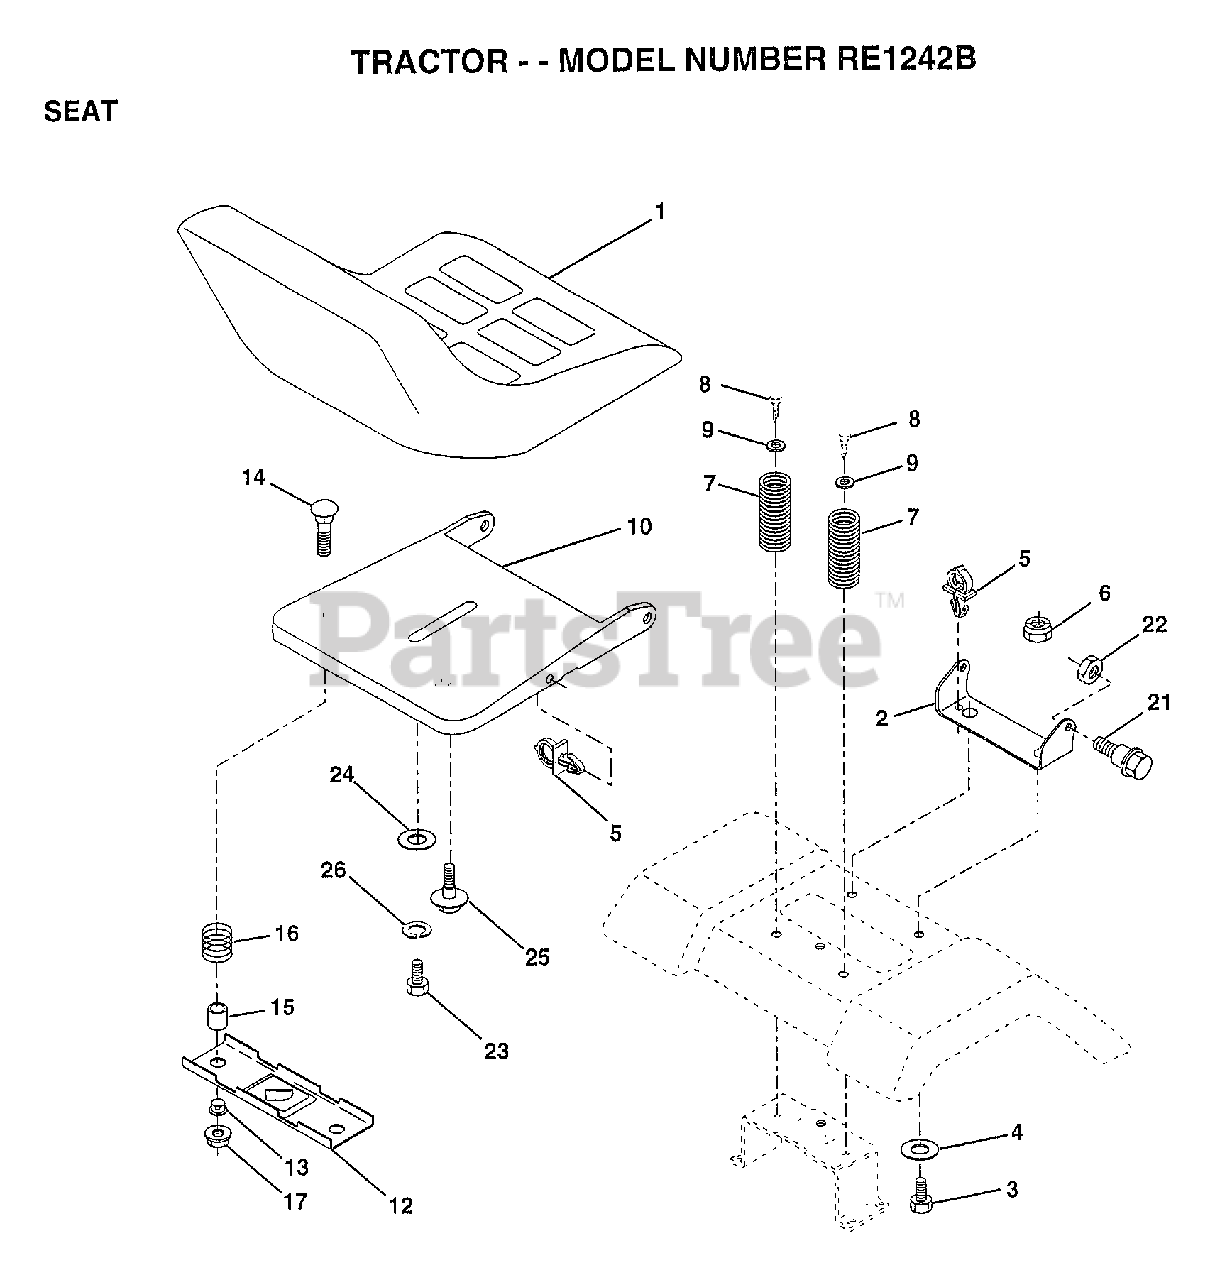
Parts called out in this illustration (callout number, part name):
2	BRACKET PVT SEAT
3	BOLT
4	WASHER PM
5	CLIP.PUSH-IN.HING
6	NUT
7	SPRING COMPRESSIO
8	SCREW GTV
9	WASHER
10	PAN-SEAT
12	BRKT SWITCH
13	BUSHING
14	BOLT-RD HD SQ NK
15	SPLIT SPACER
16	SPRING
21	"BOLT,SHOULDER"
22	NUT
23	BOLT
24	WASHER
25	"BOLT,SHOULDER"
26	LOCKWASHER
